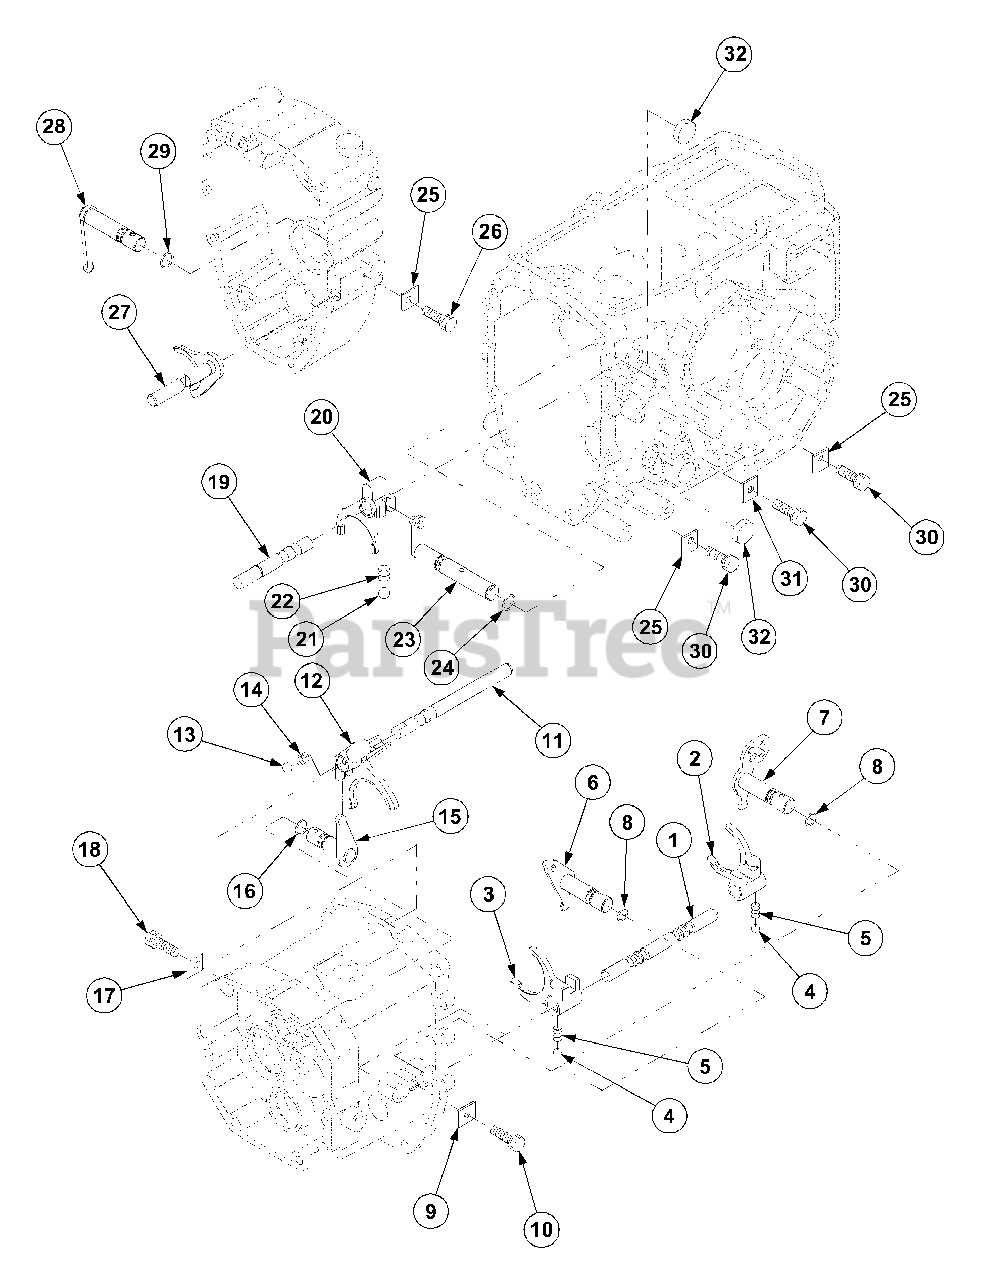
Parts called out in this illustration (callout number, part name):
2	Fork 1-2,Main
3	Fork 3-4,Main
6	Shifter A,Main
7	Shifter B,Main
10	Bolt,w/Washer
11	Rail, Shuttle - 7530 from S/N10138
12	Fork A,Shuttle
15	Shifter,Shuttle
18	Bolt,w/Washer
26	Bolt,w/Washer
30	Bolt,w/Washer
